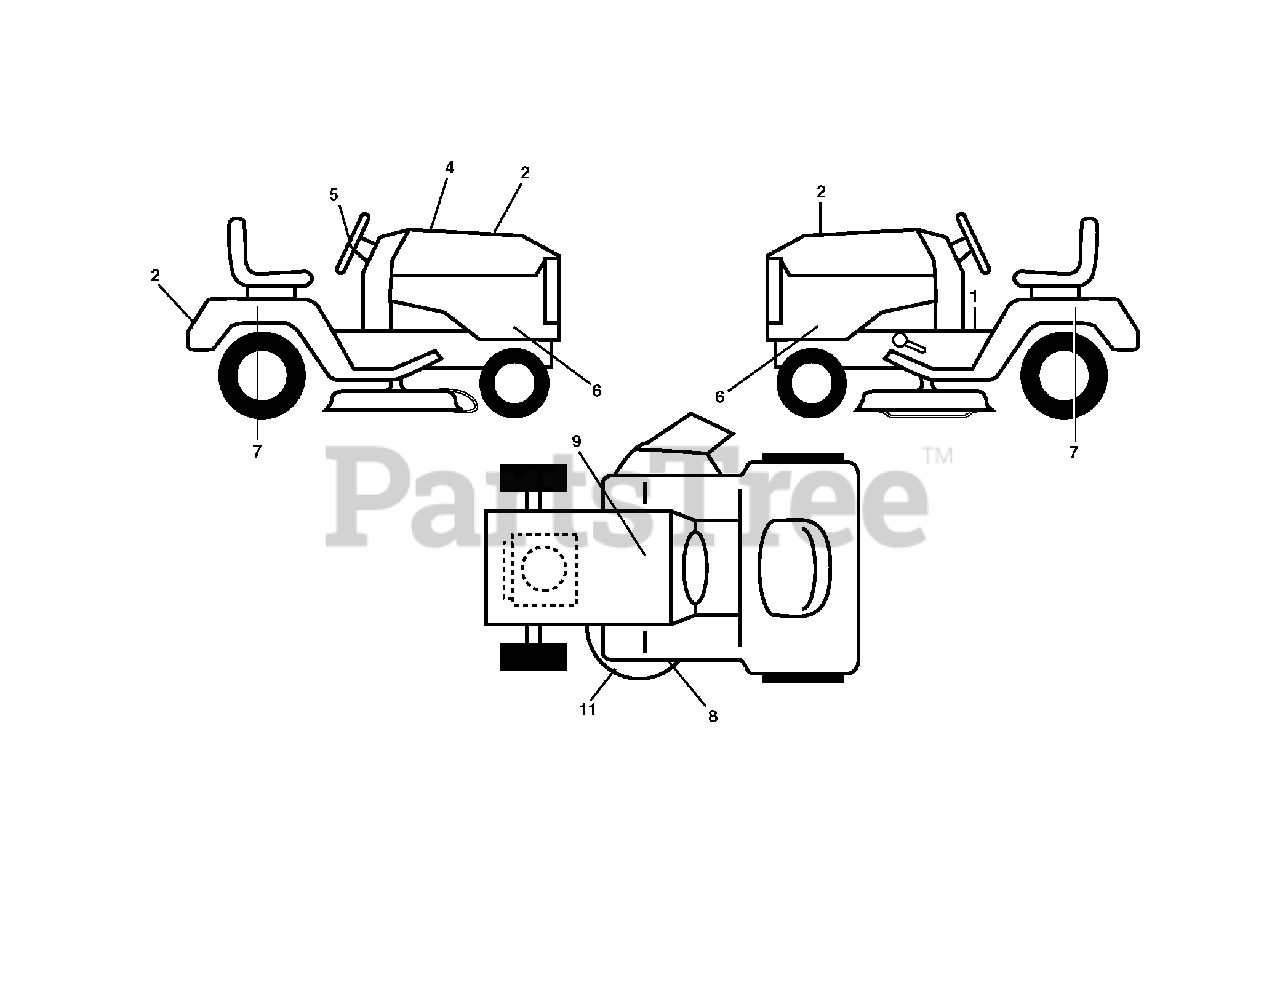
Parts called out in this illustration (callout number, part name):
1	DECAL.WARN.START.INSTRUCTIONS
2	DECAL, DIXON LOGO, DOMED
4	DECAL.RPL.KW.26HP.TGW.54.K66
5	DECAL.WHEEL.STEER.DIXON
6	DECAL.PNL.SD.26/54.KAWA.DIXON
7	DECAL.FEND.SD.GT.SERIES.DIXON
8	DECAL.MOWER.SCH.48/54
9	DECAL BTRY SYMBOLS
11	DECAL.MOWER
